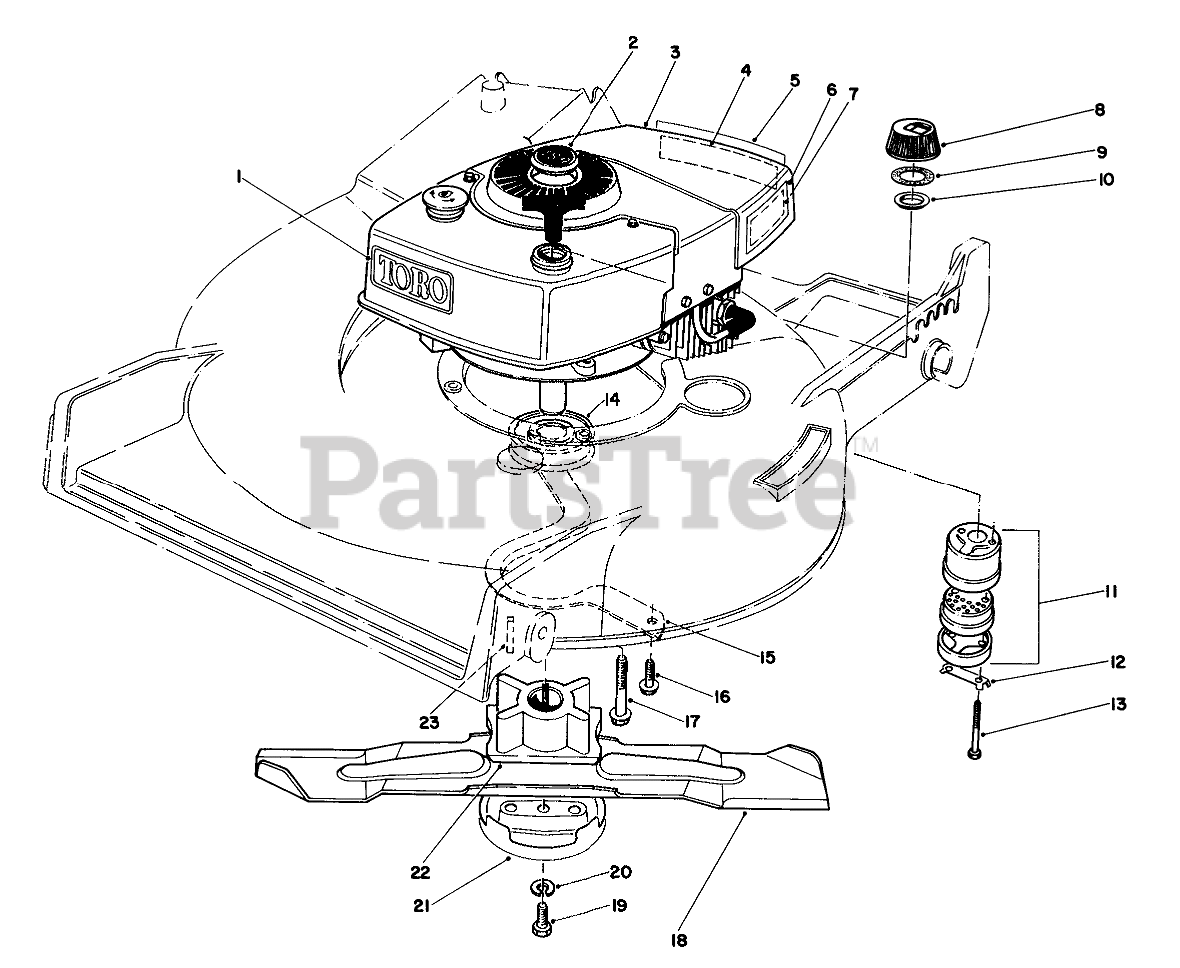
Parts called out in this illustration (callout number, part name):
1	Decal Tow
2	Plug Button
3	Engine
4	Decal Maintenance
5	Decal-Primer Bulb
6	Decal-Maintenance
7	Decal-Maintenance
8	Gas Cap (Incl. Ref. #9 & 10)
9	GASKET
10	GAS CAP BAFFLE
11	Muffler Assembly (Incl. Ref. #12 & 13)
12	CLIP - LOCKING
13	SCREW-HH
14	Pulley
15	BELT GUIDE
16	Screw
17	3/8-16 X 2 CAPSCREW
18	BLADE-21in
19	SCREW-BLADE
20	WASHER-LOCK
21	Anti Scalp Cup
22	BLADE RETAINER(DEEP)
23	KEY-SQUARE
